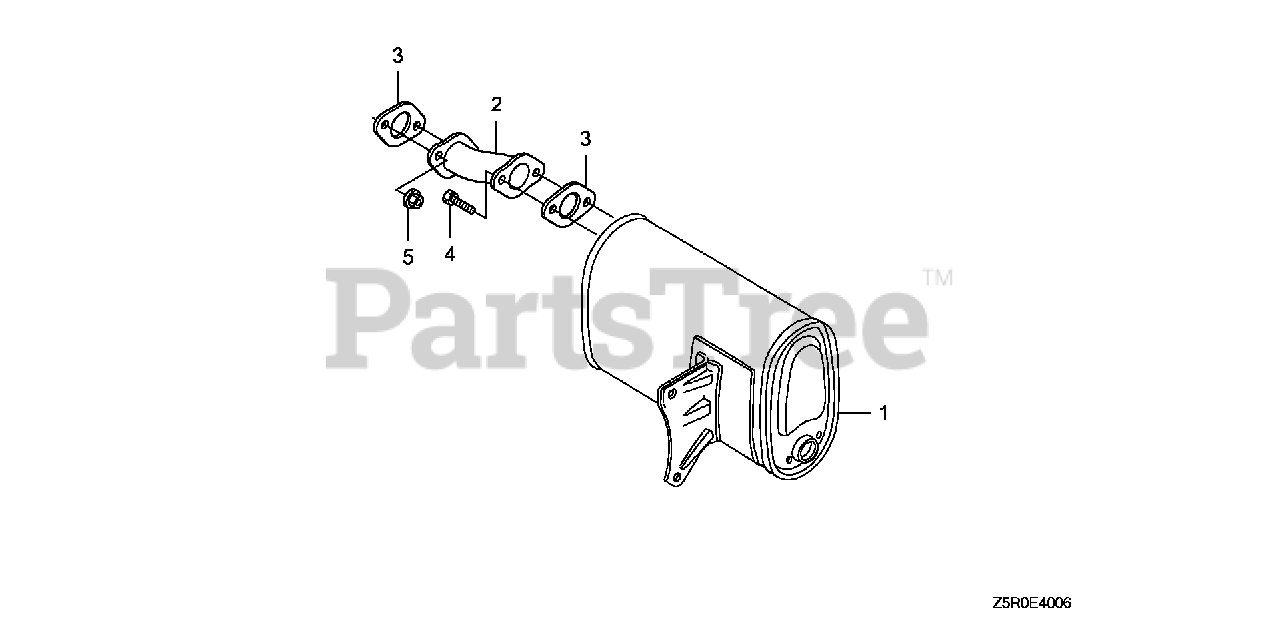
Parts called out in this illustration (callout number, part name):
3	GASKET, EX. PIPE
4	BOLT, HEX. (8X28)
5	NUT, FLANGE (8MM)
